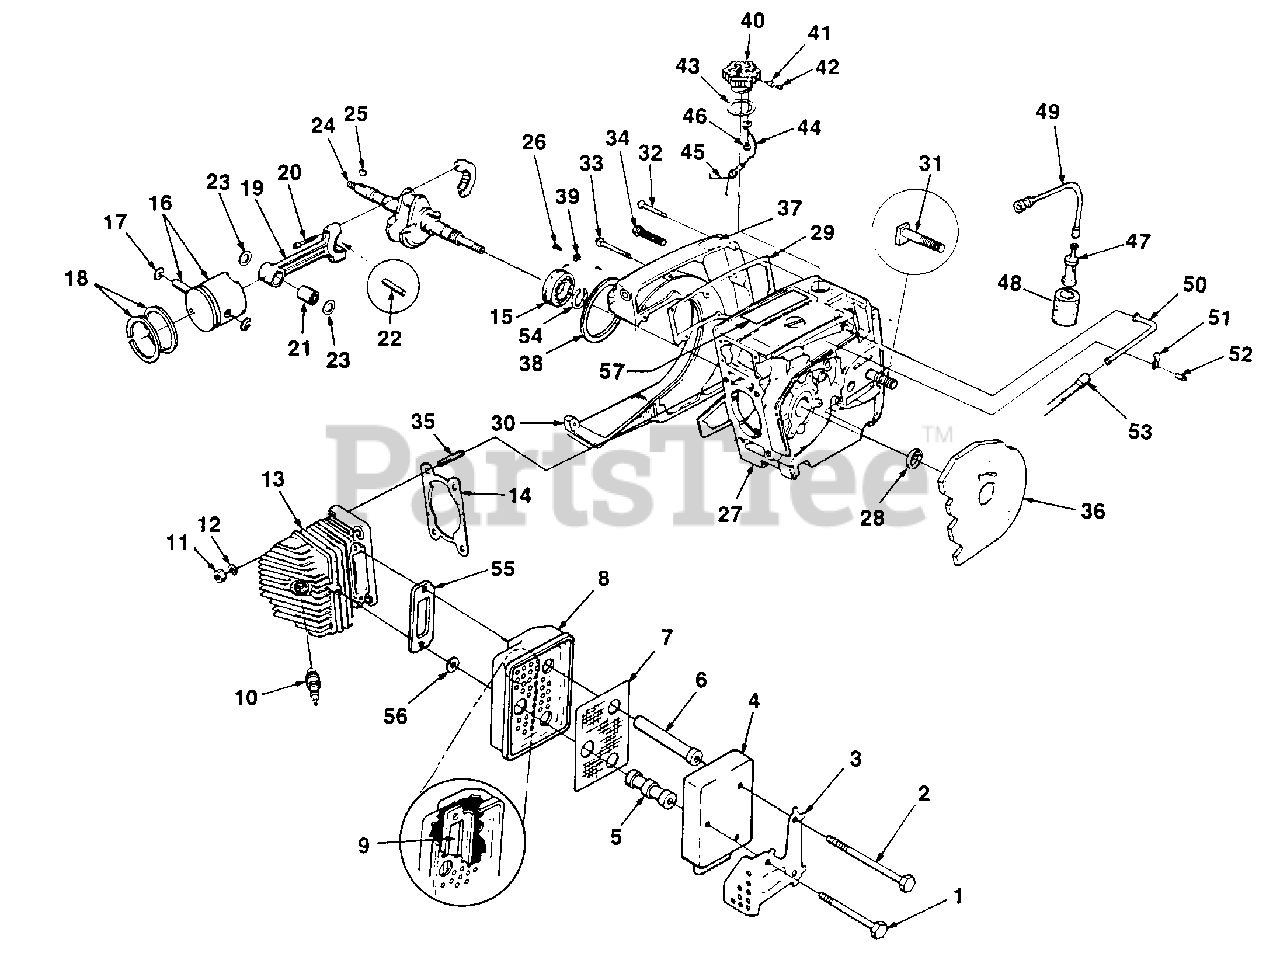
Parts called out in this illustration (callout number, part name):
2	SCREW-Hex hd. 1/4-20 x 3
3	SHIELD-Muffler
4	CAP-Muffler
5	SUPPORT-Short
6	SUPPORT-Long
7	SCREEN-Spark arrestor
8	BODY-Muffler
9	PLATE-Muffler
10	SPARK PLUG
11	NUT 1/4-28 x 3/8
12	WASHER-Lock 1/4
13	CYLINDER
14	GASKET-Cylinder
15	BEARING-Ball
16	PISTON & PIN ASSEMBLY
17	PISTON PIN RETAINING RING
18	PISTON RING
19	ROD-Connecting
20	SCREW-Hex hd. 8-32 x 1/2
21	BEARING-Needle
22	BEARING-Needle (set of 28)
24	CRANKSHAFT
25	KEY-Woodruff
26	SCREW-Torx 10-32
27	CRANKCASE
28	SEAL
29	GASKET-Oil cover
30	COVER-Fuel tank
31	BOLT-Guide
32	SCREW-Fil hd, 8-32 x 5/8
33	SCREW-Fil hd. 8-32 x 1 3/4
34	SCREW-Fil hd. 8-32 x 2 3/16
35	STUD-Cylinder
36	SHIELD-Sawdust
37	LABEL-Warning
38	"O" RING
39	WASHER-Lock
40	CAP-Fuel
41	VALVE-Check
43	GASKET-Fuel cap
45	RETAINER-Cap
47	FILTER-Fuel
48	FILTER ELEMENT
49	FUEL LINE
50	CONNECTOR
52	SCREW-Pan hd 6-32 x 5/16
53	FUEL LINE
54	RING-Retaining
55	GASKET-Muffler
56	WASHER-Flat 1/4
57	DECAL
